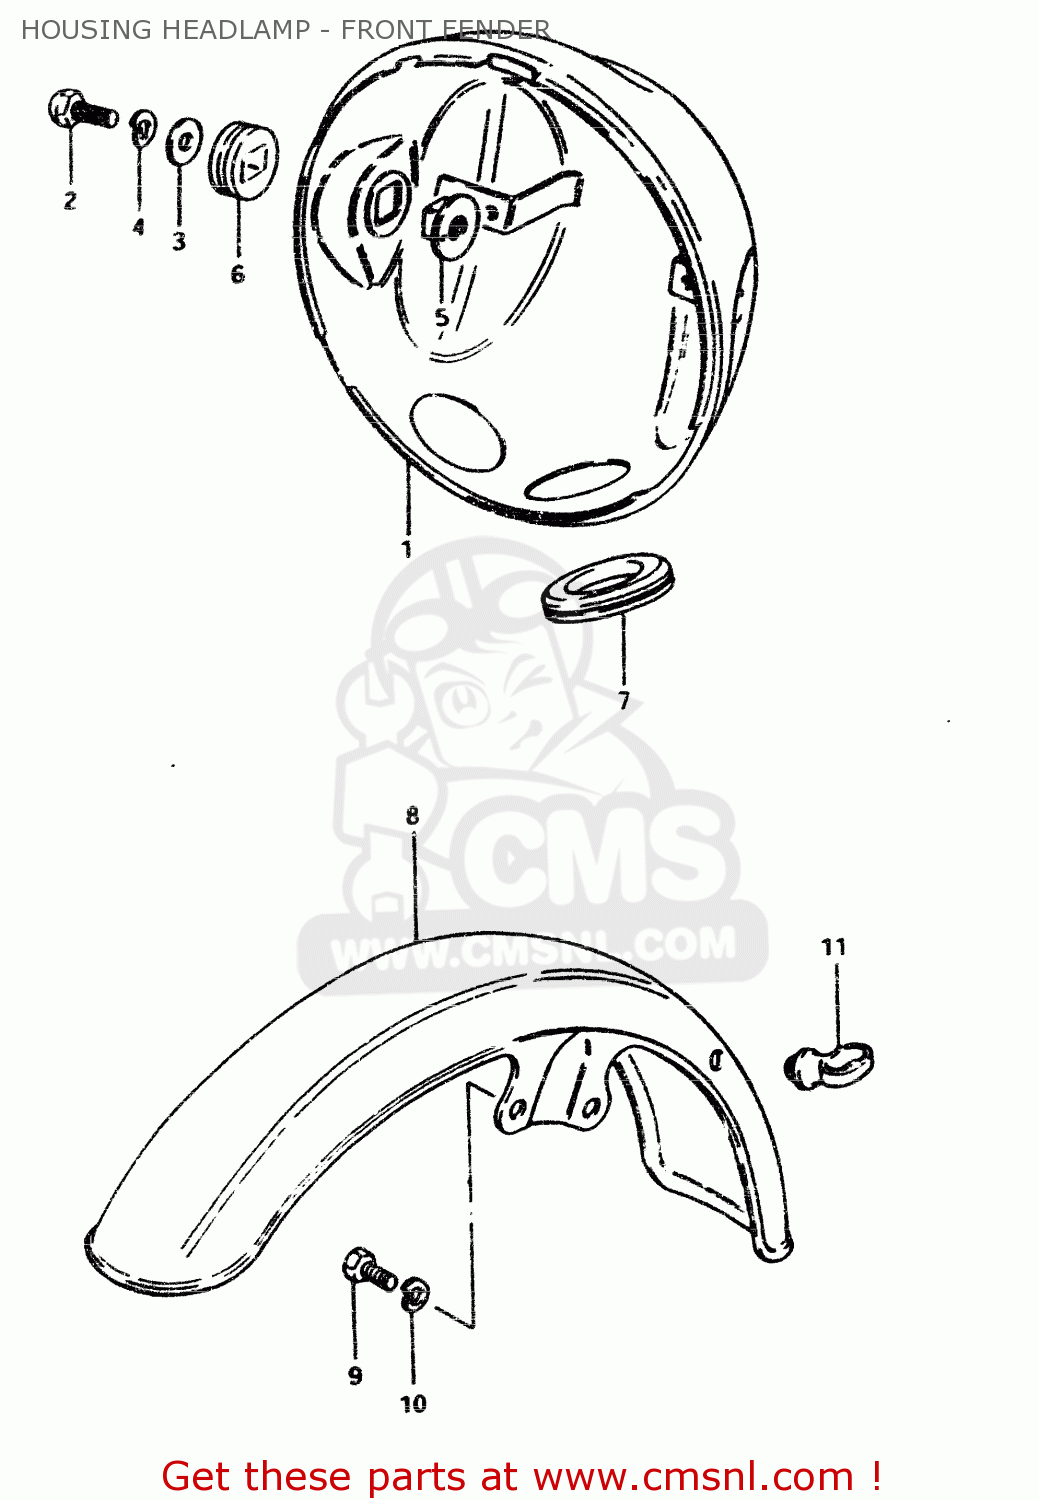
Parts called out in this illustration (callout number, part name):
1	HOUSING,HEADLAMP
2	BOLT
3	WASHER
4	LOCK WASHER
5	SPACER,HEADLAMP HOUSING
6	CUSHION,HEADLAMP HOUSING
7	GROMMET,HEADLAMP HOUSING
8	FENDER,FR
9	BOLT
10	LOCK WASHER
11	GUIDE,CABLE
